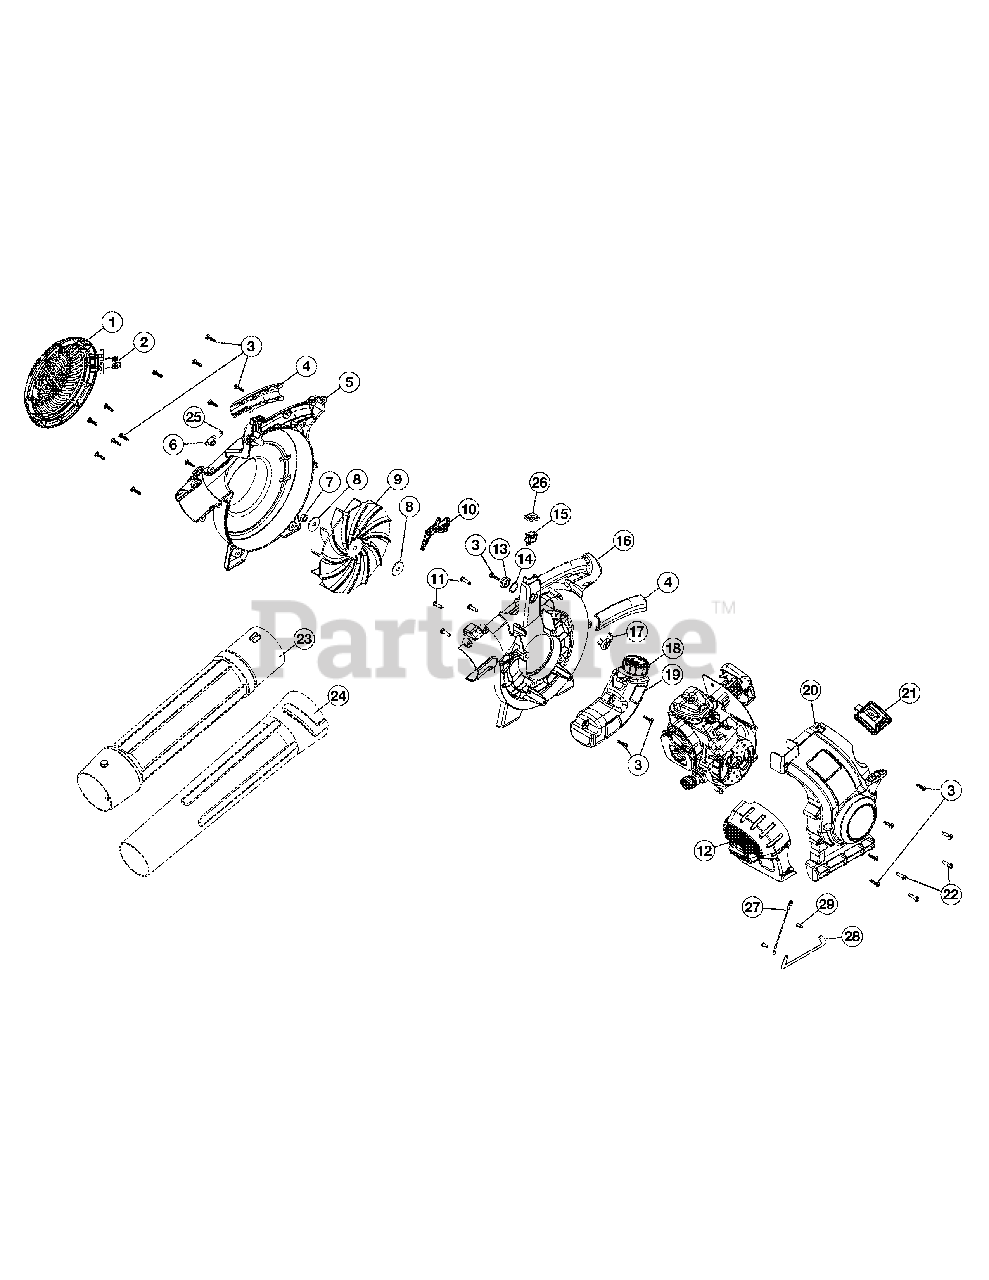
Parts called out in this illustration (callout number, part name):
1	Intake Cover
3	Screw
4	Handle Grips
5	Impeller Housing
6	Latch Tube
10	Throttle Trigger
11	Screw
12	Muffler Cover
13	Inner Trigger Lock
14	Wavey Washer
16	Impeller Housing
17	Outer Trigger Lock
19	Fuel Tank Assembly
20	Engine Cover Assembly
21	Spark Plug Cover
22	Screw
23	Upper Tube
24	Lower Tube
25	Latch Spring
26	Switch Cover
27	Wire Ground
28	Strap Ground
